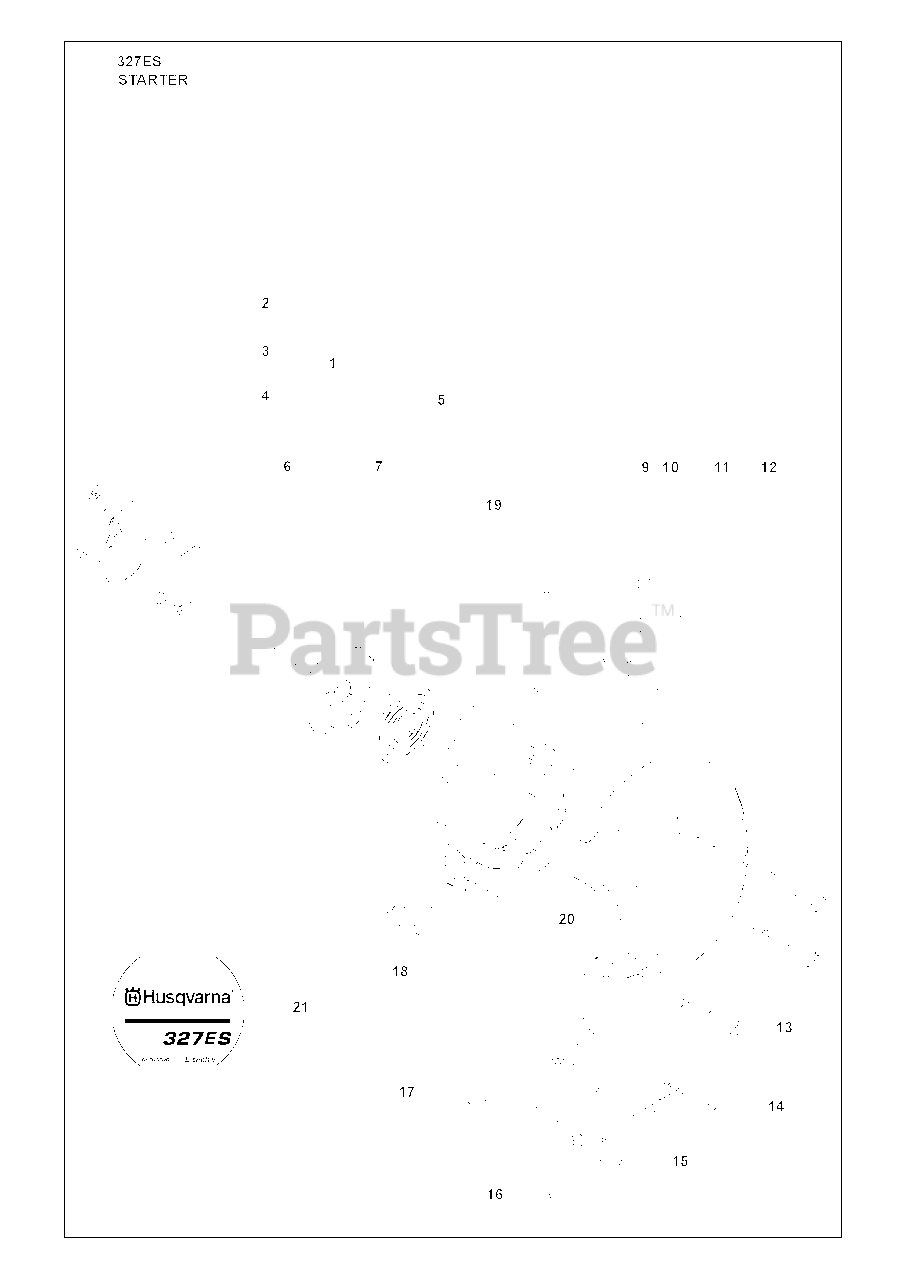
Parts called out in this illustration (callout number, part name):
1	STARTER PAWL BRIDGE
4	STARTER PAWL
5	STARTER ASSY
7	STARTER PULLEY ASSY.
8	SPACING SLEEVE
9	STARTER ROPE
10	STARTER HANDLE
11	STARTER HOUSING
12	SPACING SLEEVE
18	BRACKET ASSY
21	DECAL STARTER HSG
